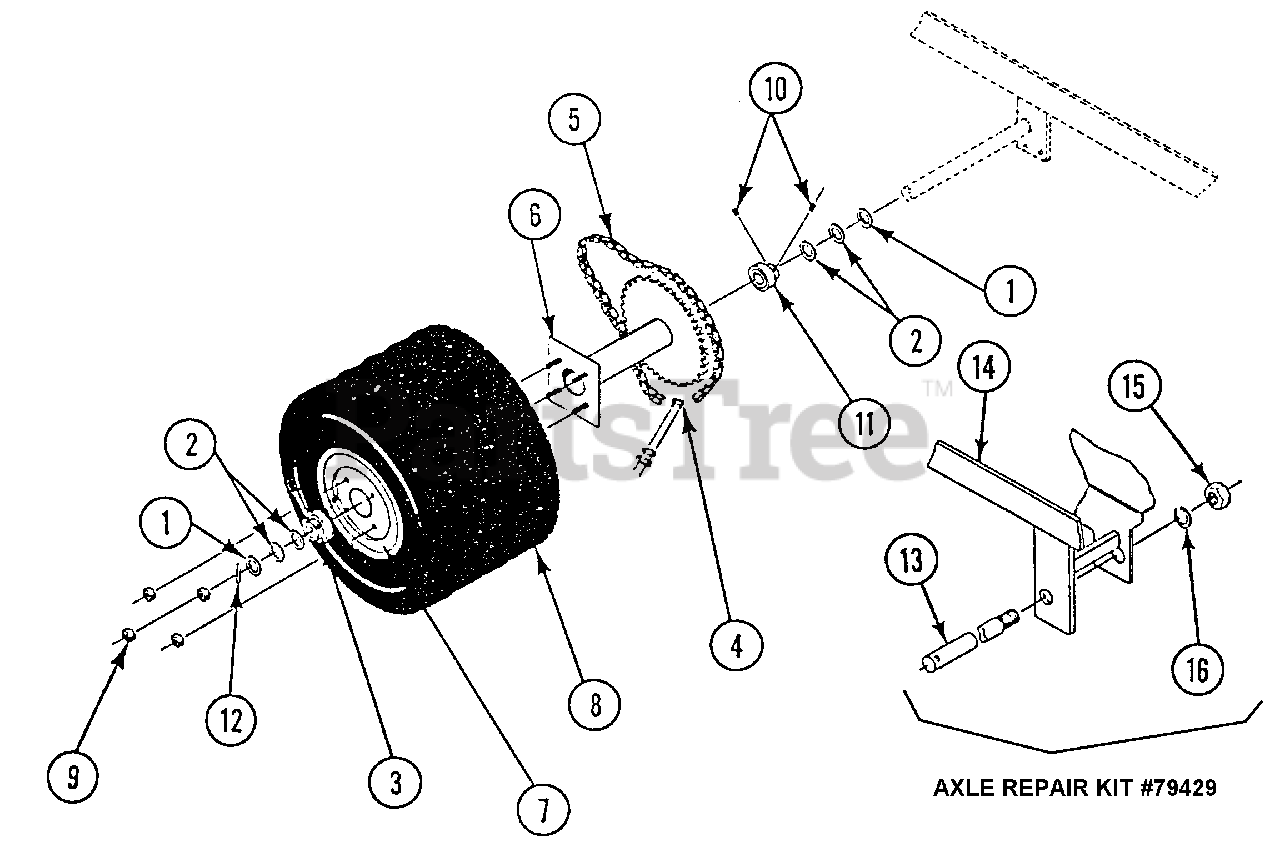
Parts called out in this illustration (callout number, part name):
1	WASHER, 1-1/2 OD X 1 ID X 1/16 THK
2	WASHER l-1/2 OD X 1 ID X 1/8 THK
3	BEARINGS 1" BORE, W/COLLAR
4	MASTER LINK, #50 CHAIN
5	CHAIN, #50 ("LB" FRAME) 56 ROLLERS
5	CHAIN, #50 ("S" & "LK" FRAME) 60 ROLLERS
6	DRIVE WHEEL HUB WELDMENT
7	WHEEL, W/RIM & TIRE ("S" FRAME)
7	WHEEL, W/RIM & TIRE ("LB" & "LK" FRAMES)
8	TIRE 18/9.50 X 8 ("S" FRAME)
8	TIRE 20/10 X 10 ("LB" & "LK" FRAMES)
9	LUG NUT, 60 DEG, 1/2-20
10	SETSCREW, 1/4-28 X 5/16, W/NYLOC
11	BEARINGS 1" BORE, WITH COLLAR
11	WITHOUT COLLAR
12	PIN, SPIROL, 5/16 X 1-1/2, STD DUTY
13	AXLE, REMOVEABLE
15	NUT, 7/8-14
16	LOCKWASHER, 7/8 SPLIT SPRING
79429	AXLE REPAIR KIT
